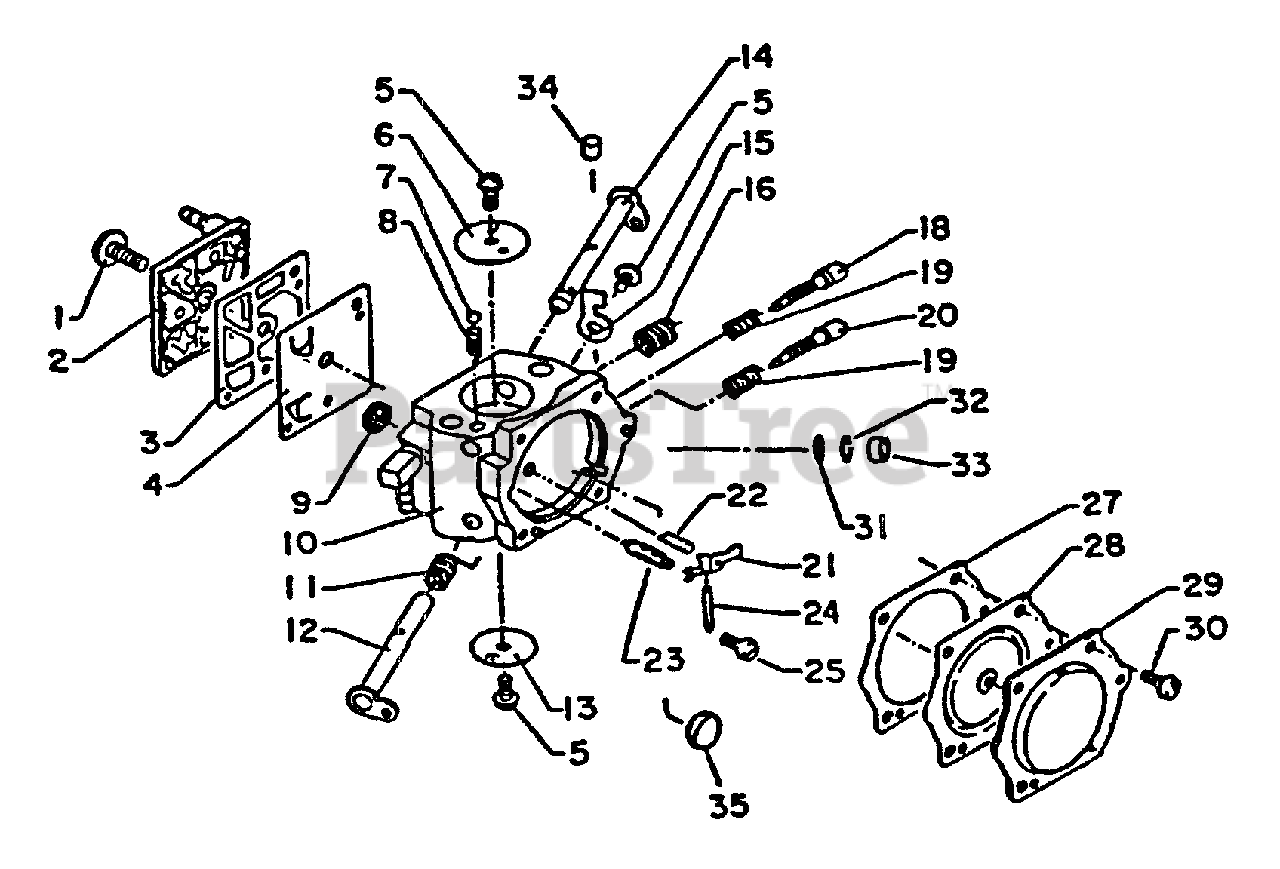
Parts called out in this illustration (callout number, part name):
1	SCREW, PUMP COVER
2	COVER, PUMP
3	GASKET, PURGE
4	DIAPHRAGM, PURGE
6	VALVE, CHOKE
7	BALL, CHOKE
9	STRAINER
10	BODY, CARBURETOR
11	SPRING, THROTTLE RETURN
12	SHAFT, THROTTLE
13	VALVE, THROTTLE
14	SHAFT, CHOKE
15	STOP, THROTTLE
16	SPRING, IDLE ADJUST
18	NEEDLE - LOW SPEED
19	SPRING, LOW SPEED NEEDLE
20	NEEDLE - HIGH SPEED
21	LEVER, METERING
22	SPRING, METERING LEVER
23	VALVE, INLET NEEDLE
24	PIN, METERING LEVER
25	SCREW
27	GASKET, METERING
28	DIAPHRAGM, METERING
29	COVER, METERING
30	SCREW
31	STRAINER
32	RING, RETAINING
33	PLUG, WELCH
34	PLUG
35	PLUG, WELCH
